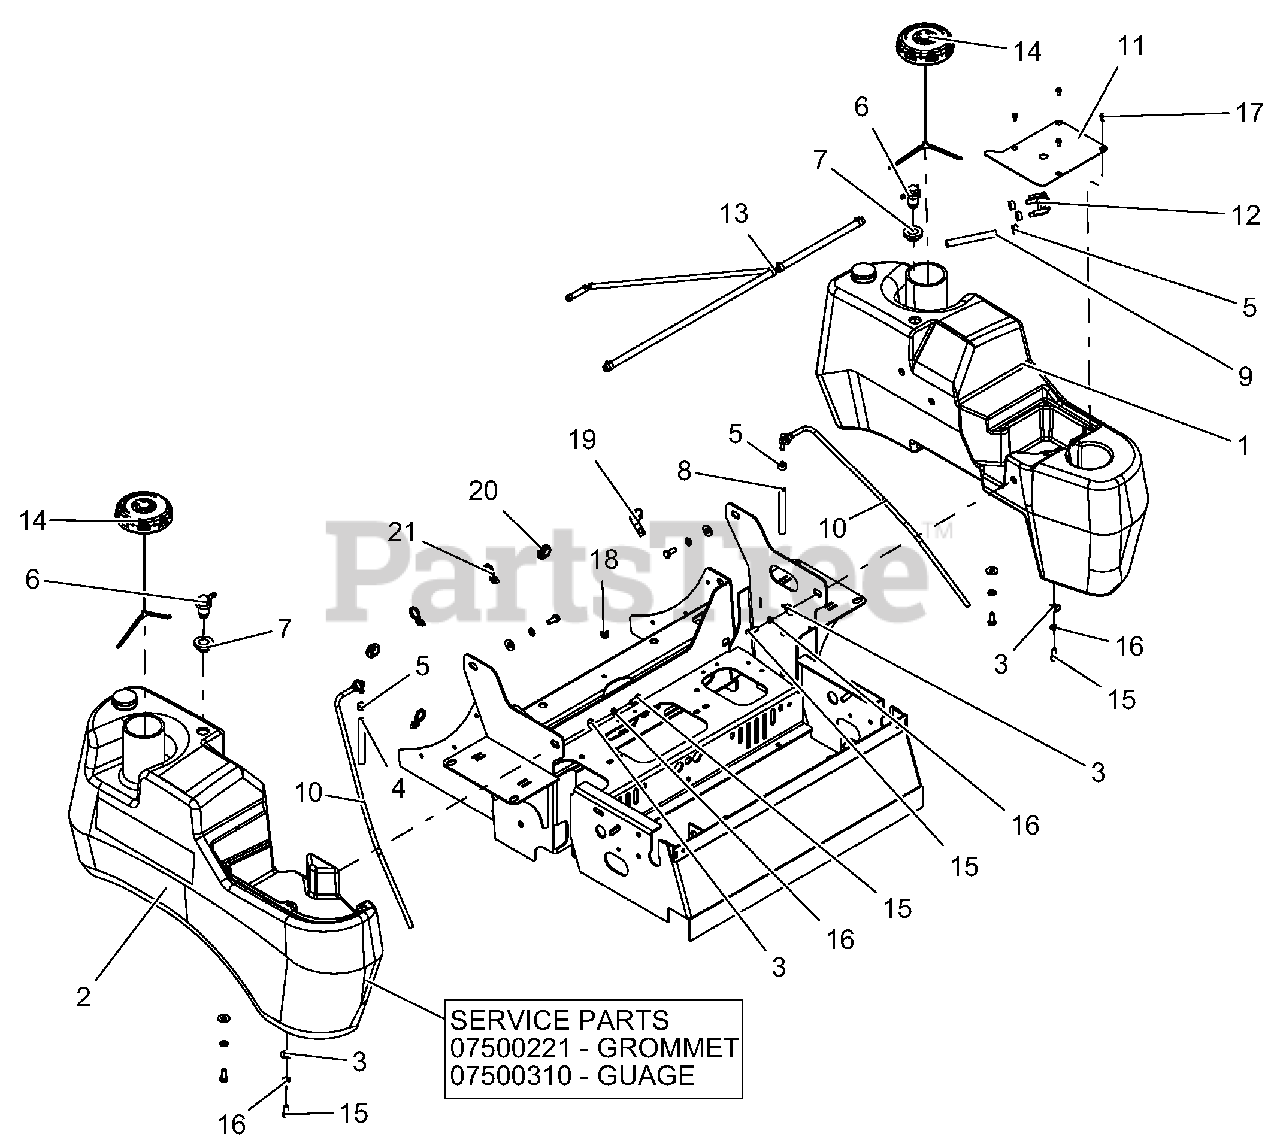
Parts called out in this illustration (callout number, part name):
1	ASSY-LH LARGE FUEL TANK W/MECH GAUGE-GAS
2	ASSY-RH LARGE FUEL TANK W/MECH GAUGE-GAS
3	WSHR-FL-STL.38X.875X.083 YWZC
4	.25 LOW-PERM GAS HOSE 54.00" LG - RH TANK TO VALVE
5	CLAMP, FUEL LINE
6	VALVE, COMBINATION
7	GROMMET, REMOTE VENT NITRILE
8	.25 LOW-PERM GAS HOSE 19.00" LG - LH TANK TO VALVE
9	.25 LOW-PERM GAS HOSE 28.00" LG - Valve to engine
10	ASM, LARGE TANK FUEL PICKUP
11	PLATE, FUEL VALVE MOUNTING-RED
12	VALVE, FUEL
13	PT400, FUEL LINE ASSEMBLY
14	CAP, FUEL VENT-IN AUTOLOCK
15	BLT-HEX .31-18X.75 GR5 YWZC
16	WSHR-LK .31X.078 REG YWZC
17	SCR-MCH 10-24X.38 HWHSTAINLESS
18	CLIP, ROUTING (.50 ID)
20	GROMMET, RUBBER
21	CABLE TIE W/ TREE (.25 HOLE)
